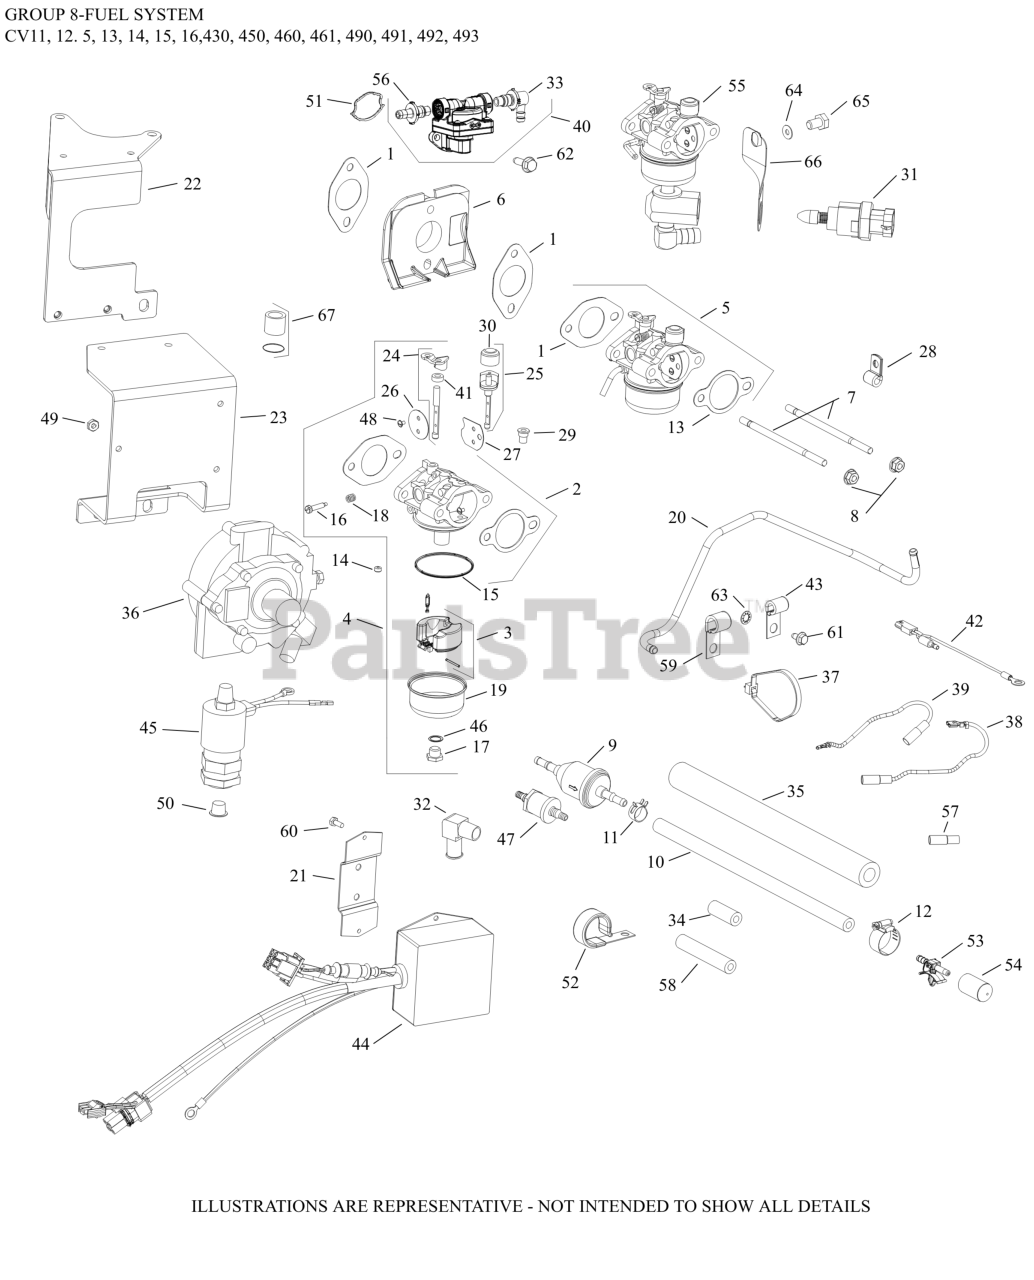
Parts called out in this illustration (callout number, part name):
1	GASKET, CARBURETOR
2	KIT, HIGH ALTITUDE (+10,000 FT)
3	KIT, REPAIR FLOAT (WALBRO)
4	KIT, REPAIR CARB (PUMP FEED) (WALBRO)
4	KIT, REPAIR BOWL (WALBRO)
6	DEFLECTOR, HEAT
7	STUD,M6X1.0X116
8	NUT, FLG M6X1.0
9	FILTER,FUEL 75 MICRON (GRAVTY FEED)
12	CLAMP, HOSE (KM)-USE 25 237 31-S
13	GASKET, AIR CLEANER BASE
14	SEAL, SOLENOID
15	GASKET, FUEL BOWL
46	GASKET, BOWL SCREW
NI	KIT, REPAIR CHOKE (WALBRO)
NI	CARBURETOR W/GASKETS - USE 12 853 140-S
NI	LINE, FLEXIBLE FUEL-DISCONTINUED
